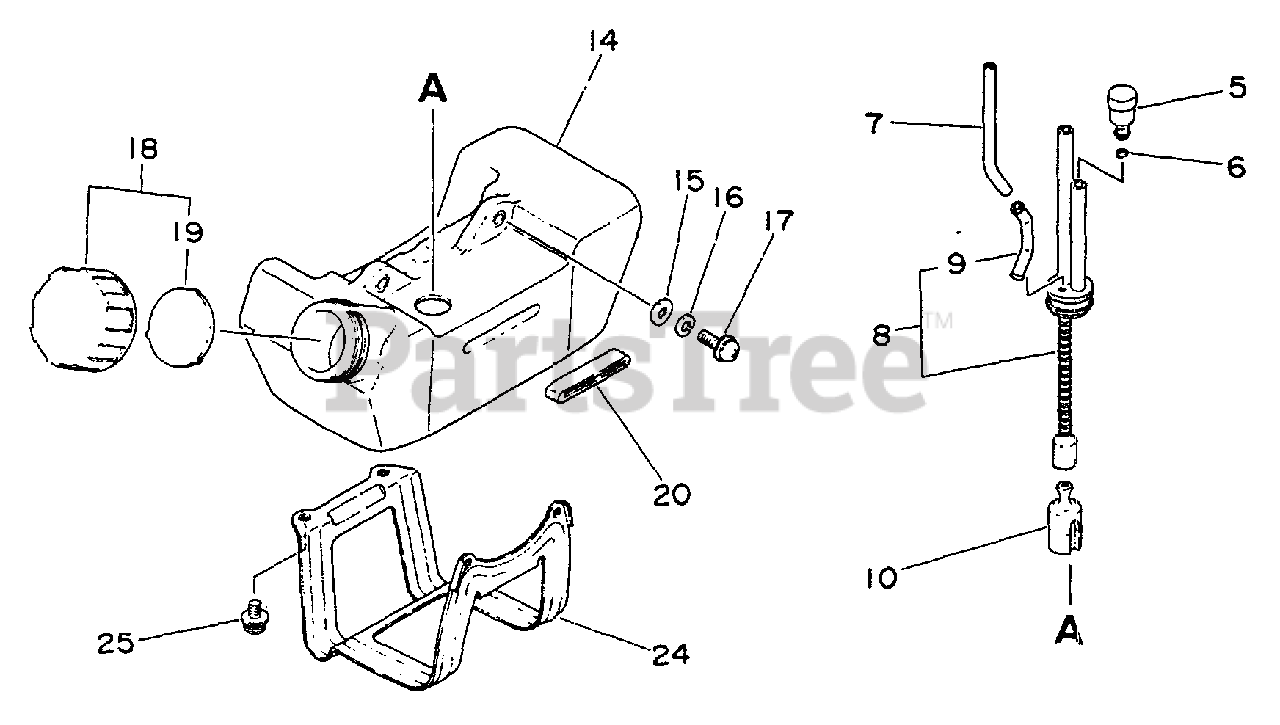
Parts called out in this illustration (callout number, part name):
5	VENT ASSY
7	PIPE, FUEL 3×6×75 CLEAR
8	PIPE KIT, FUEL
9	CONNECTOR, PIPE
10	FILTER, FUEL
14	TANK, FUEL
15	WASHER 5.5×12×0.8
16	WASHER, SPRING 5
17	SCREW 5×16
18	CAP ASSY
19	GASKET
20	CUSHION, FUEL TANK
24	GUARD, FUEL TANK
25	SCREW 5×10
